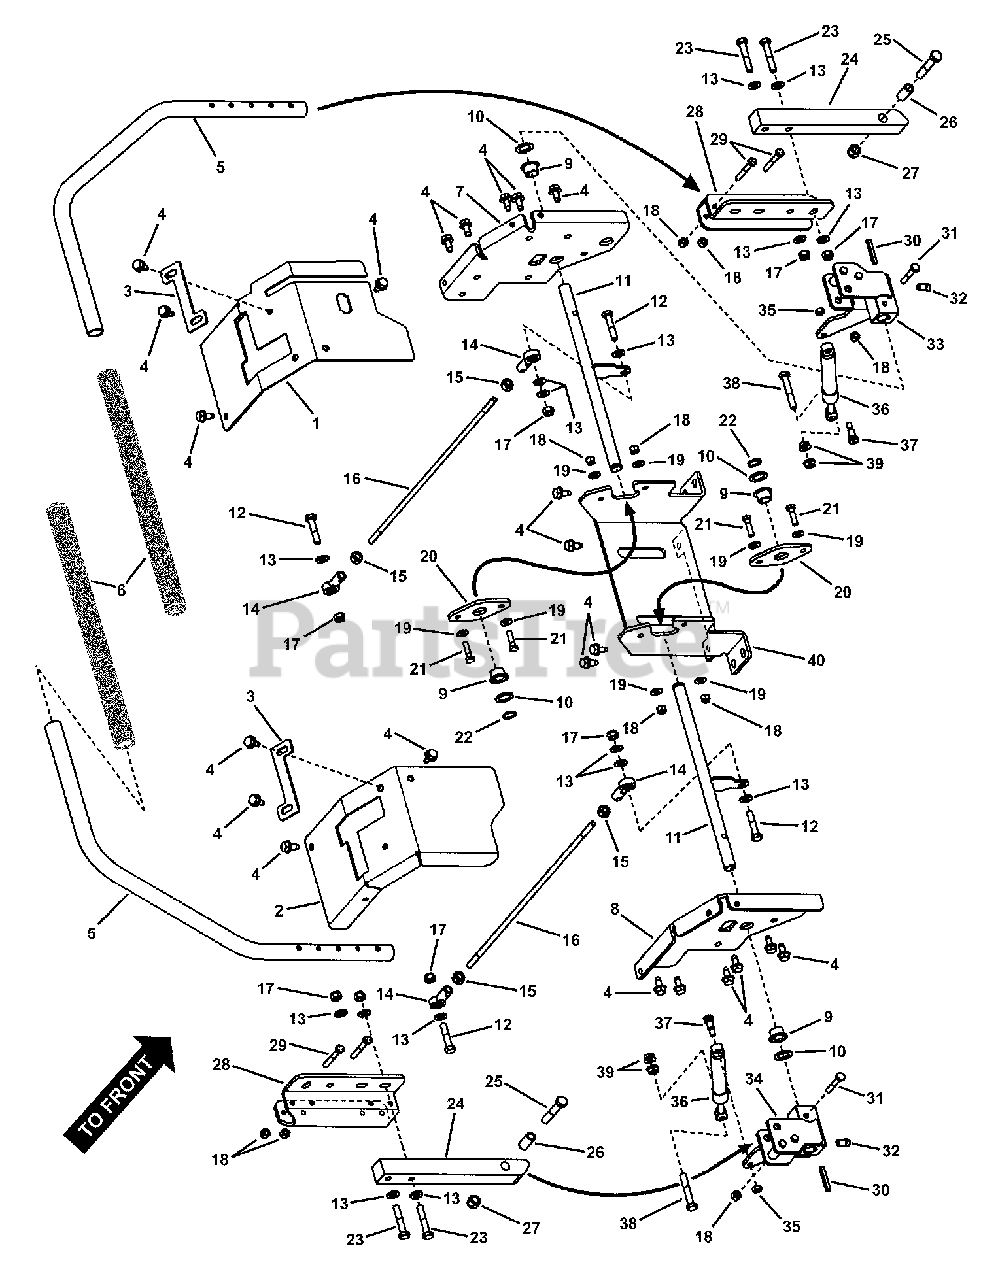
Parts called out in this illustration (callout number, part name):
1	LIMITER BRKT, LH
2	LIMITER BRKT, Twin Stick, Right Side, LFNZM
3	BRACKET, Speed Control
4	SCREW, 5/16-18 x 5/8" Hex Washer Self-Tap
5	HANDLEBAR, Twin Stick, LFNZM
6	FOAM GRIP, Handle
7	BUSHING MOUNT PLATE, LH
8	BUSHING MOUNT PLATE, Right Side, LFNZM
9	BUSHING, Teflon Impregnated
10	WASHER, .64 I.D. x .99 O.D. x .05 Flat
11	WELDMENT, Shaft Twin
12	SCREW, 5/16-18 x 1-1/2" Hex Head Cap, GR 5
13	WASHER, 5/16" Flat
14	ROD END (5/16-24 thread)
15	NUT, 5/16-24 Hex, GR 5 or B
16	LINKAGE, Pump Control (5/16-24 threads)
17	NUT, 5/16-18 HEX NYLON LOCK
18	NUT, 1/4-20 HEX NYLON LOCK
19	WASHER, 1/4" Flat
20	MOUNTING PLATE, Left Hand Bearing
21	SCREW, 1/4-20 x 1" Hex Head Cap GR 5
22	RING, 5/8" External Retaining
23	BOLT, 5/16-18 X 1-3/4 GD5 YZ
24	MOUNTING ARM, Twin Stick
25	SCREW 3/8-16 x 2" Hex Head Cap, GR 5
26	SPACER, .498 O.D. x 1.010" long
27	NUT, 3/8-16 HEX NYLON LOCK
28	BRACKET, Handle Adjustment
29	SCREW, 1/4-20 x 1-3/4" Hex Head Cap, GR 5
30	KEY, 3/16" Square x 1-1/2"
31	SCREW, 1/4-20 x 1-1/2" Hex Head Cap GR 5
32	SET SCREW, 5/16-18 x 1/2" Square Head Cup Point
33	MOUNTING HUB WELDMENT, T-Stick LH
34	MOUNTING HUB WELDMENT, T-Stick RH
35	NUT, 1/4-20 Hex Center Lock
36	DAMPENER, Hydraulic
37	SCREW, Shoulder Socket Head
38	BOLT, 5/16-18 X 2", GD5
39	NUT, 5/16-18 Hex Flange Lock
40	CENTER BRACKET, Joystick
